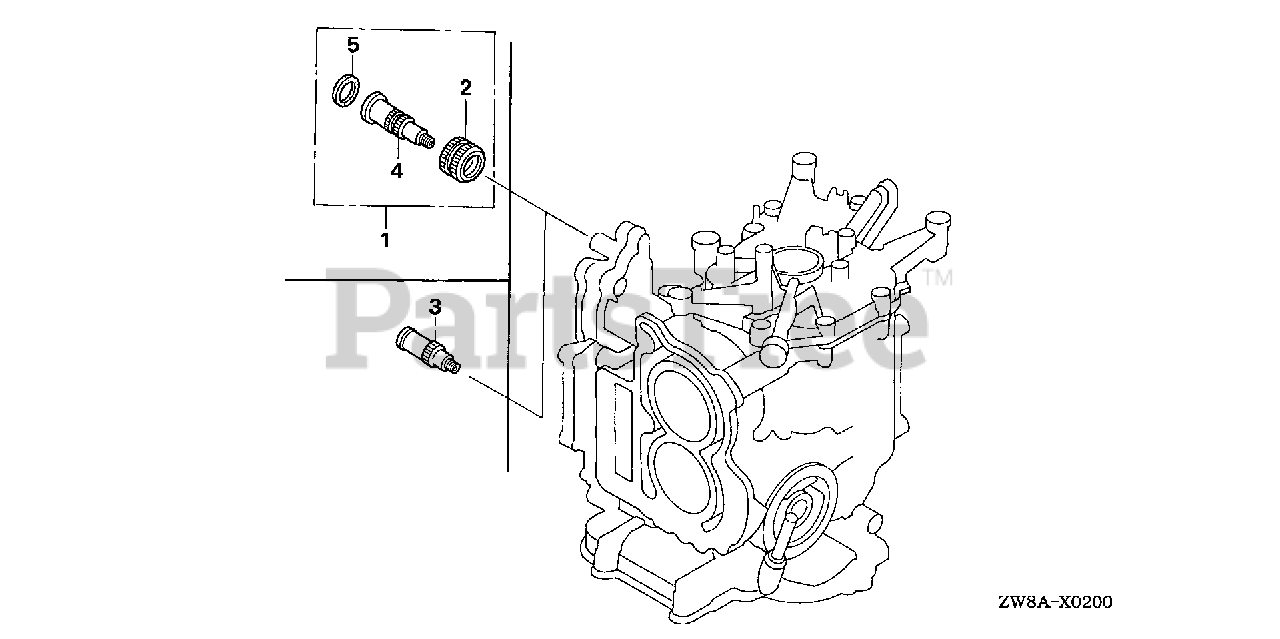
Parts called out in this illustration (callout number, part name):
1	JOINT KIT, WATER HOSE
2	NUT, WATER MOUTH
3	JOINT, WATER HOSE
4	JOINT, WATER HOSE
5	SEAT, WATER MOUTH
